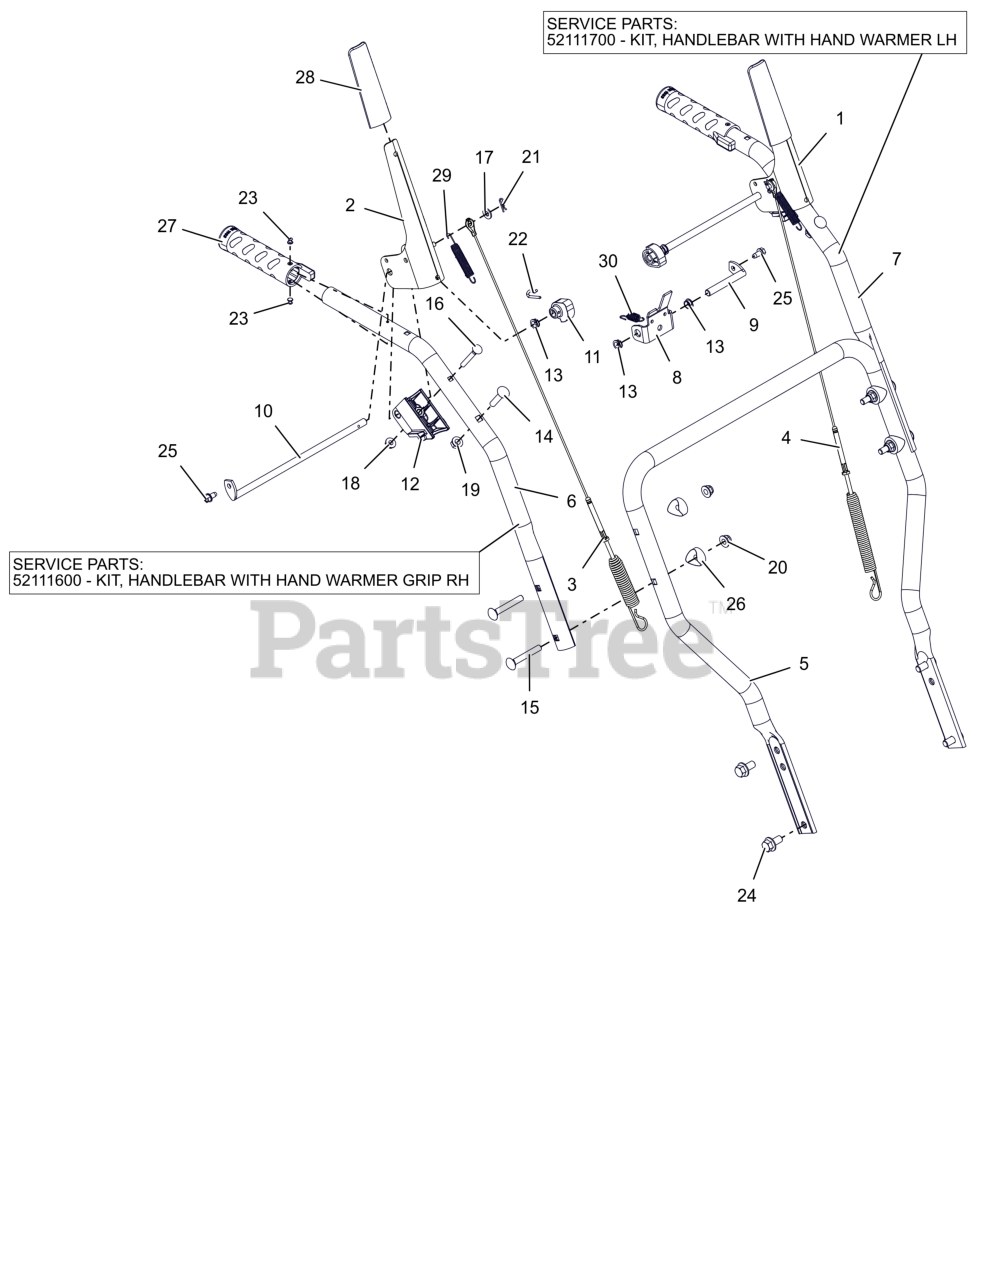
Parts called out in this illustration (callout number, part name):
1	LEVER, CLUTCH-LH
2	LEVER, CLUTCH-RH
3	CABLE, AUGER (DELUXE & PRO)
4	CABLE, UPPER TRACTION
5	HANDLEBAR, LOWER
6	HANDLEBAR, UPPER - RH
6	KIT, HANDLEBAR HG RH
7	HANDLEBAR, UPPER - LH
7	KIT, HANDLEBAR HG LH
8	BRACKET, INTERLOCK ARM
9	ROD, PIVOT - INTERLOCK
10	ROD, PADDLE MOUNT - PRO
11	CAM, INTERLOCK
12	BLOCK, CLUTCH PADDLE
13	BUSHING, POLYLINER-.38 SNAPIN
14	BLT,RHSN .31-18X1.50 G5 ZCC
15	BLT-RHSN.31-18X2.25 G5 TBZ 120
16	BLT-RDHDXLSQNK .25-20X2.0 G5YZ
17	WSHR,FLT .281X.625X.065 ZCC
18	NUT-LK-CTR-FLG .25-20 ZC120
19	NUT-LK-TOP-FLG .312-18 GF ZCC
20	NUT-NYL-FLG.31-18 GF TBZ 120WR
21	PIN, HAIR #178 .06X.77 ZCC
22	PIN, SPRING CLIP
23	RVT-POP #43 .125X.313 STL ZINC
25	SCR-TAP .25-20X.50 HWH ZCC
26	SPACER, HANDLEBAR
27	GRIP- HEATED HANDLE - BLACK
28	SLEEVE- CLUTCH PADDLE
29	SPRING, EXTENSION
30	SPRING-EXT .047X.438X1.45
